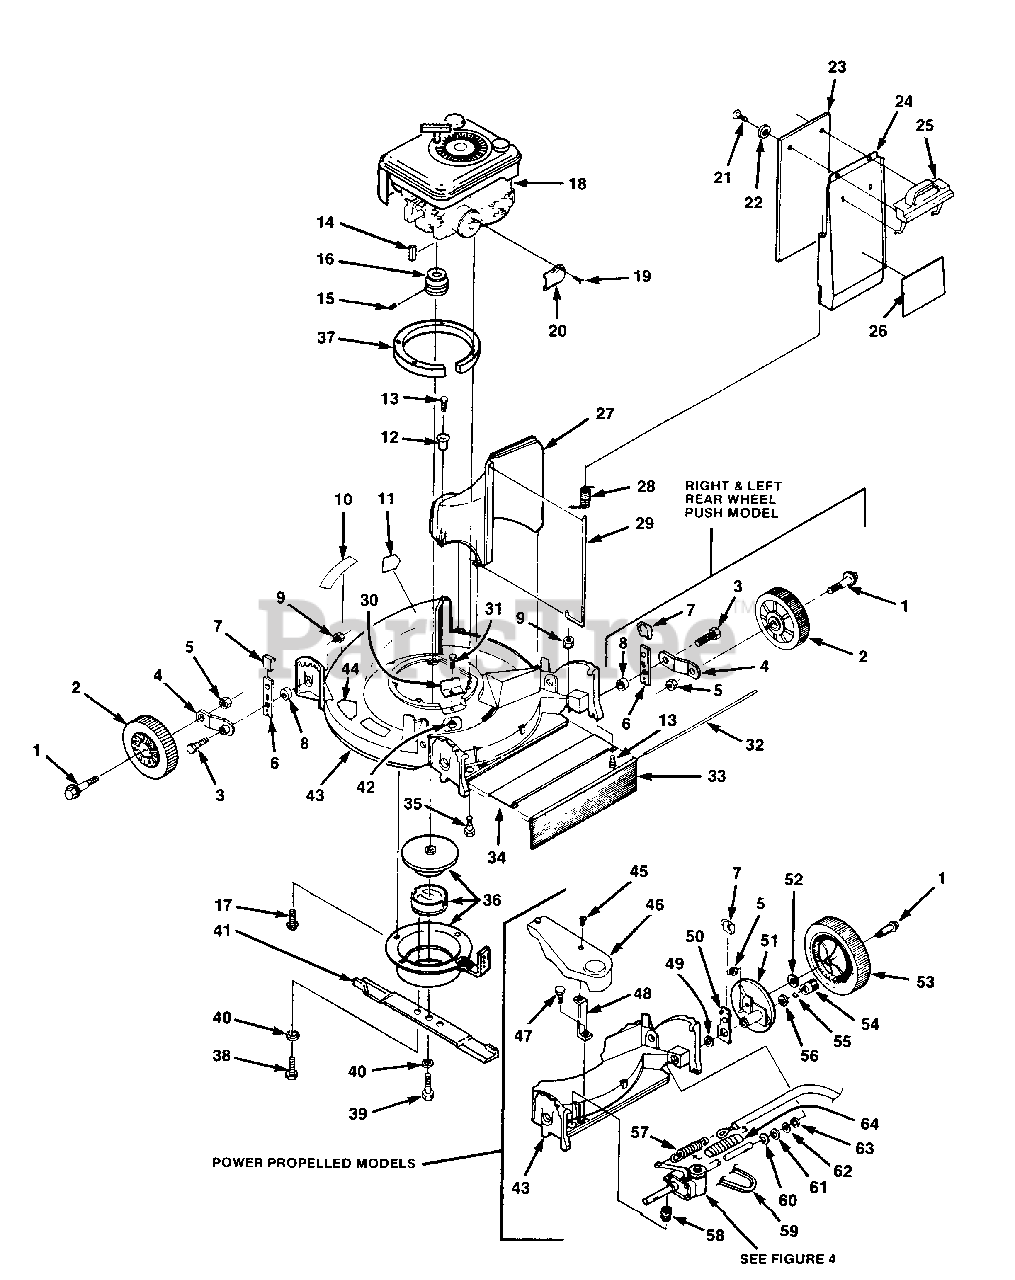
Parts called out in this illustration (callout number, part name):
1	BOLT- Axle
2	WHEEL & TIRE ASSEMBLY
4	WHEEL- Adjuster arm
5	NUT- 3/8-24
6	SPRING
7	KNOB
9	NUT- Flange 5/16-20
10	DECAL- Product ID
11	DECAL- Warning
12	SIMPSON EYELET
13	SCREW- 1/4-20 x 3/4
14	KEY- 5/8 x 5/32
15	SCREW- Set 8/32
16	PULLEY- Drive
17	SCREW- (5/16 - 18)
18	ENGINE- 3.5 H.P.
19	SCREW- #8-32 x 3/8
20	DEFLECTOR
21	SCREW- 1/4-10 x 5/8
22	WASHER- Plain 1/4
23	DAMP- Flap
24	DOOR- Chute
26	DECAL- Door
28	SPRING
29	PIN- Hinge
30	COVER- Belt opening
31	SCREW- 1/4-20 x 1/2
32	ROD- Drag flap
33	FLAP- Drag
35	SCREW- 3/8-16 x 2 1/4
36	BLADE/BRAKE/CLUTCH
37	RING- Engine
38	SCREW- 3/8-16 x 1
39	SCREW- 3/8-24 x 2
40	WASHER- Lock 3/8
41	BLADE-21"
42	NUT- 1/4-20
43	DECK ASSEMBLY
44	DECAL- Foot pad
45	SCREW- 1/4-20 x 3/4
46	COVER- Drive
47	SCREW- Hex #10-16
51	DRIVE WHEEL SUPPORT ASSY.
53	WHEEL & TIRE
54	PINION (R.H.)
55	PAWL- Pinion
57	SPRING- Extension
58	SPRING- Compression
59	BELT- Drive
60	RING- Eaton
64	COVER- Spring
